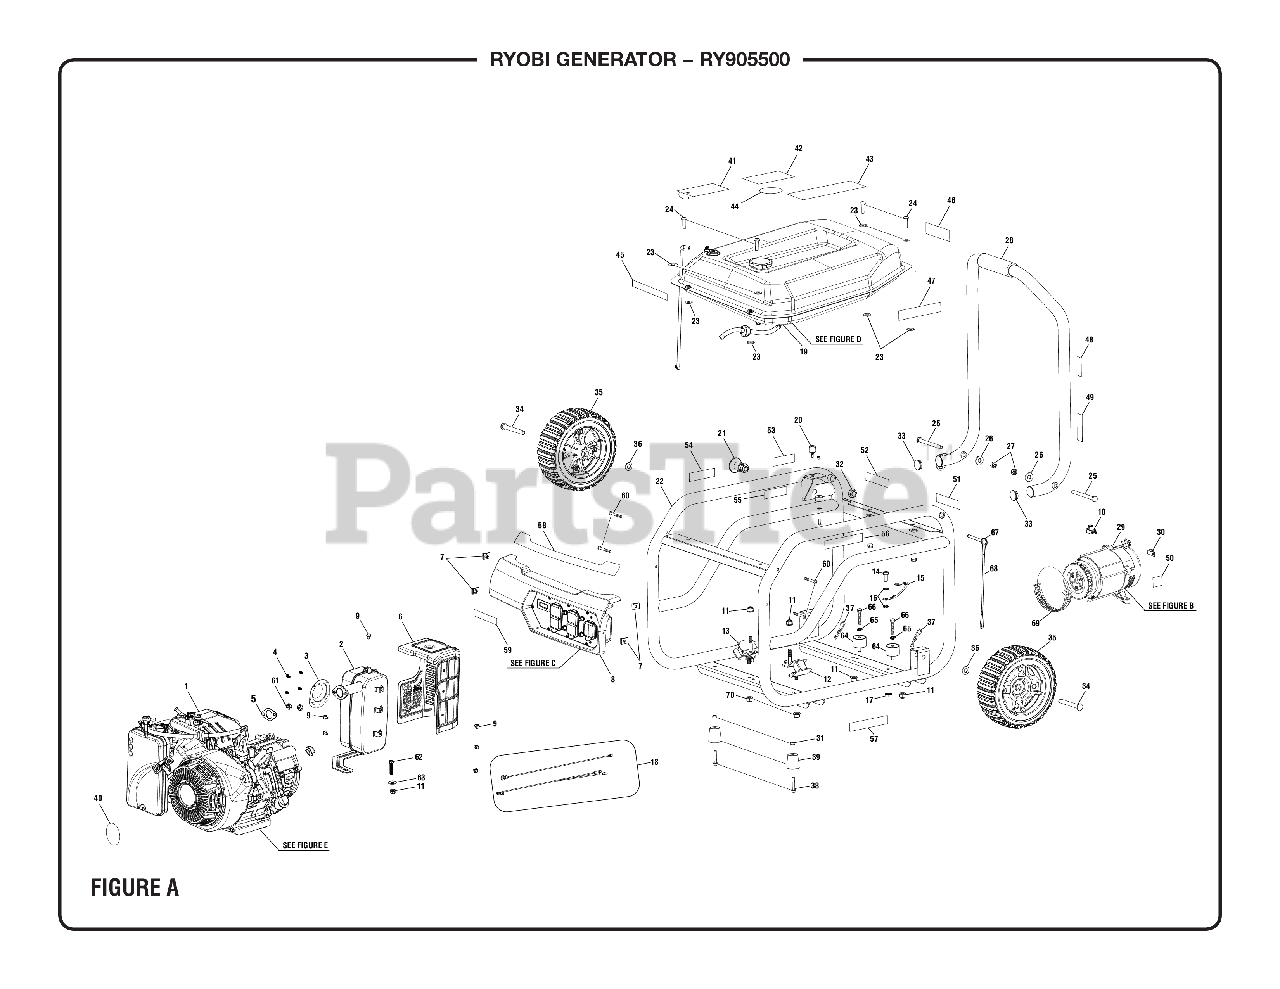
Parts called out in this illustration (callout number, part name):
3	Spark Arrester Screen
4	Screw (8-32 x 3/8 in., Pan Hd.)
5	Exhaust Gasket
6	Heat Shield
7	U-Clip (M6)
8	Control Panel Assembly
9	Bolt (M6 x 9 mm, Hex Flange Hd.)
10	Rubber Wire Protector
11	Lock Nut (M8 x 1.25 mm, Flange)
12	Engine Isolator (Large)
13	Engine Isolator (Right)
14	Bolt (5/16-18 x 3/4 in., Hex. Hd.)
15	Assembly, ground wire
16	Washer (5/16 in., External Star)
17	Flange Nut (5/16-18, Hex Hd.)
18	Wire Assembly
19	Fuel System
20	Rubber Bumper
21	Quick Release Pin Assembly
22	Carrier Assembly
23	Washer (1/4 in., Type A)
24	Screw (1/4-20 x 1 in., T30 Torx Hd.)
25	Handle Pivot Pin (5/6-18 x 90 mm)
26	Washer ( 5/16 in.)
27	Lock Nut (5/16-18, Hex Hd.)
28	Handle Assembly
29	Generator Head Assembly (See Fig. A)
30	Ground Lug (5/16-24) (BM903600)
31	Lock Nut (M8 x 1.25)
32	Lock Nut (1/2-20, Hex)
34	Washer (M10)
35	Handle Isolator
36	Washer (OD19.75 x ID10.5 x 1t)
37	Hitch Pin (M3)
38	Bolt (M8 x 1.25 in., Flange Hex Hd.)
39	Foot Assembly
40	Engine Recoil Label
41	Warning Hangtag
42	Warning Label
43	CPSC (English) Label
44	Remove Cap Fuel Stabilizer Label (English)
45	Logo Label
46	UL Fire Warning Label Spark Arrestor)
47	Start Label
48	Fuel Stabilizer Label (French/Spanish)
49	No E85 Label
50	Ground Label Icon
51	Ground Warning Label
52	Risk of Fire Danger Label
53	Quick Release Pin Label
54	Inquires Label (Ryobi)
55	Hot Surface and Exhaust Label
56	Fire Distance Label (Eng/Sp)
57	Engine Lubricant Label
58	Performance Label
59	Choke Label
60	Screw (M6 x 50 mm, T30 Torx Pan Hd. )
61	Hex Nut (M8 x 1.25, Special)
62	Screw (M8 x 40 mm, Hex Hd.)
63	Washer (ID9 x OD25.4 x 2t)
64	Isolator Generation 7
65	Lock Washer (OD14.8 x ID8.5 x 1t)
66	Bolt (M8 x 1.25 in., Hex Hd.)
67	Release Pin (5/16 x 2 in.)
68	Lanyard (3/16 in.)
69	Fan Cover (Generator Head)
70	Lock Nut (5/16-18)
